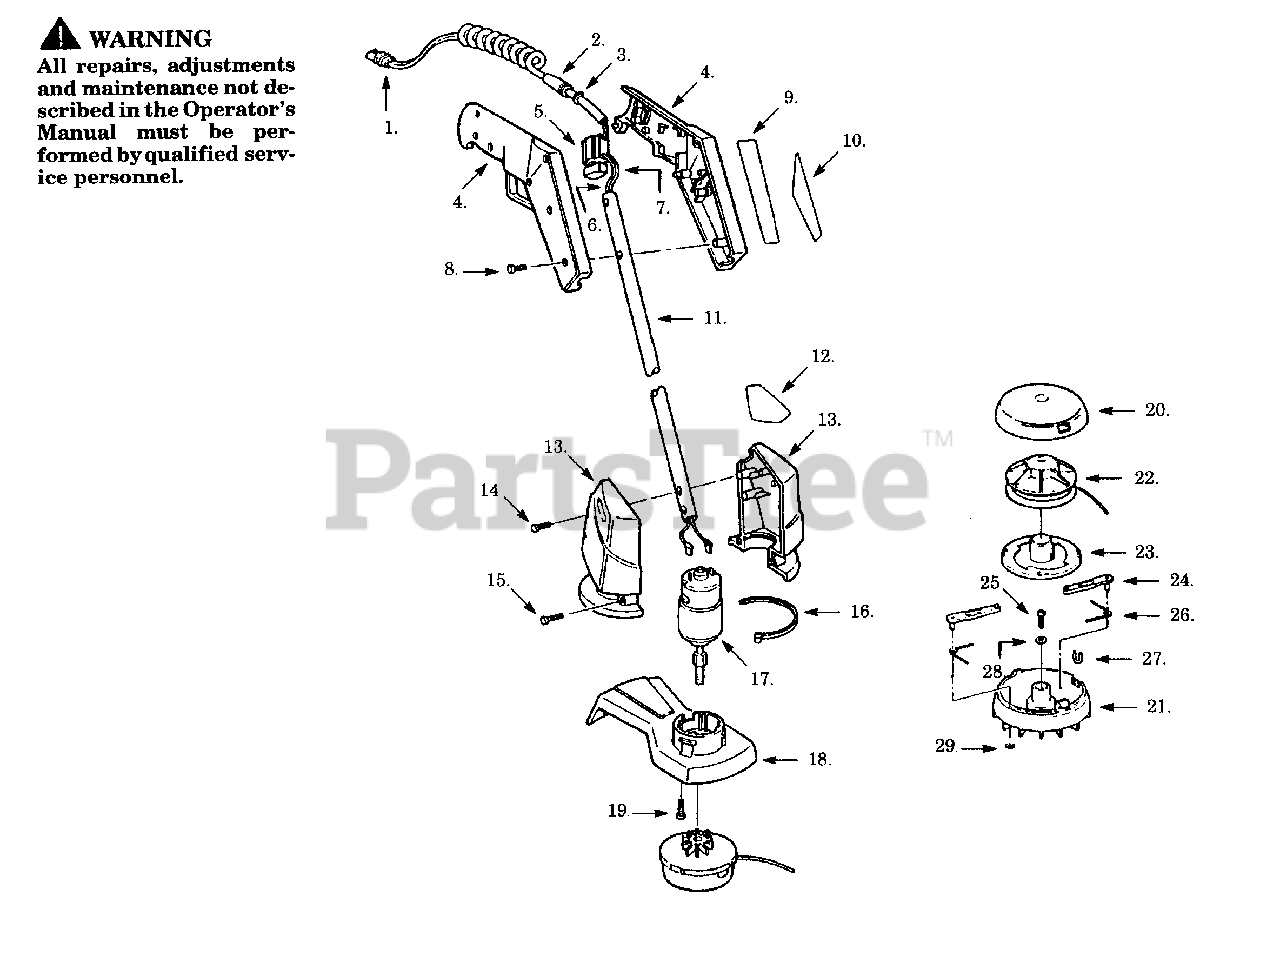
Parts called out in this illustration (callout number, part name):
2	Rubber Strain Relief
3	Strain Relief
4	Handle Set
5	Trigger Switch
6	Lead Wire (Black)
7	Lead Wire (Red)
9	Handle Decal (Not a serviceable part)
10	Warning Decal (Not a serviceable part)
12	Hsg. Top Decal (Not a serviceable part)
13	Housing Set
16	Tie Wrap
17	Motor/Adapter Assy
18	Guard/Blade Assy.
21	Housing Assy.
22	Spool & Line
27	Line Shield
